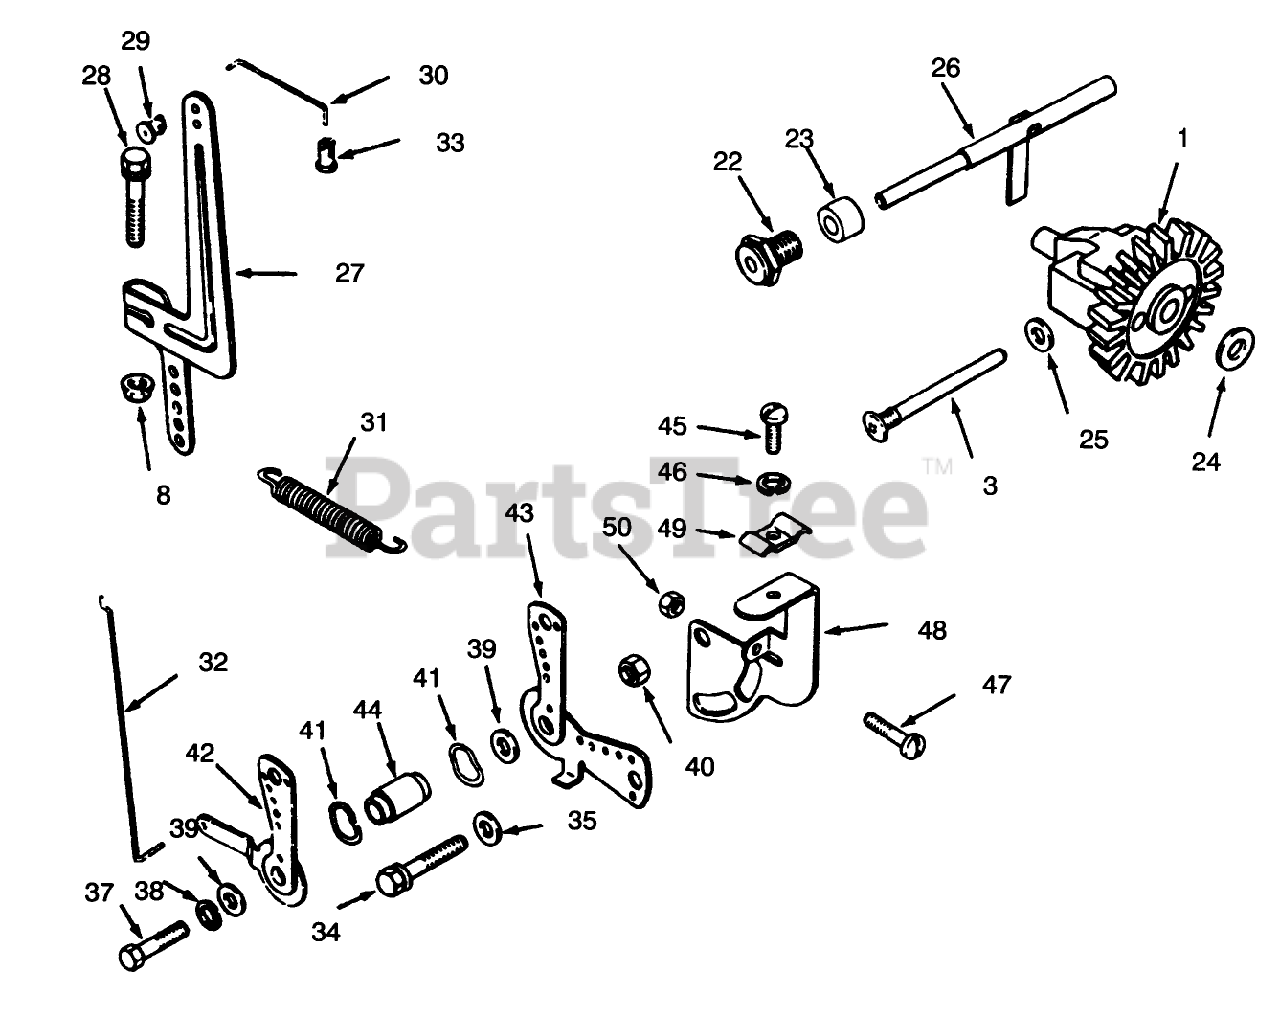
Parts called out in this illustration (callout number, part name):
1	KOHLER A-235743-5
3	KOHLER 231355
8	KOHLER X-799-1
22	KOHLER 235476
23	KOHLER X-400-80
24	KOHLER 237022
25	KOHLER 25-468-01
26	KOHLER A-235256-5
27	KOHLER 47-090-20
28	KOHLER X-776-1
29	KOHLER 47-158-07
30	KOHLER 47-079-10
31	KOHLER 47-091-01
32	KOHLER 47-079-01
33	KOHLER 25-158-09
34	KOHLER X-132-6
35	KOHLER X-25-72
37	KOHLER X-5-26
38	KOHLER X-20-1
39	KOHLER X-25-63
40	KOHLER X-76-2
41	KOHLER 275690
42	KOHLER 47-090-07
43	KOHLER 47-090-08
44	KOHLER 47-112-02
45	KOHLER X-67-51
46	KOHLER 25-468-04
47	KOHLER 232556
48	KOHLER 47-126-09
49	KOHLER 47-237-02
50	KOHLER X-72-4
